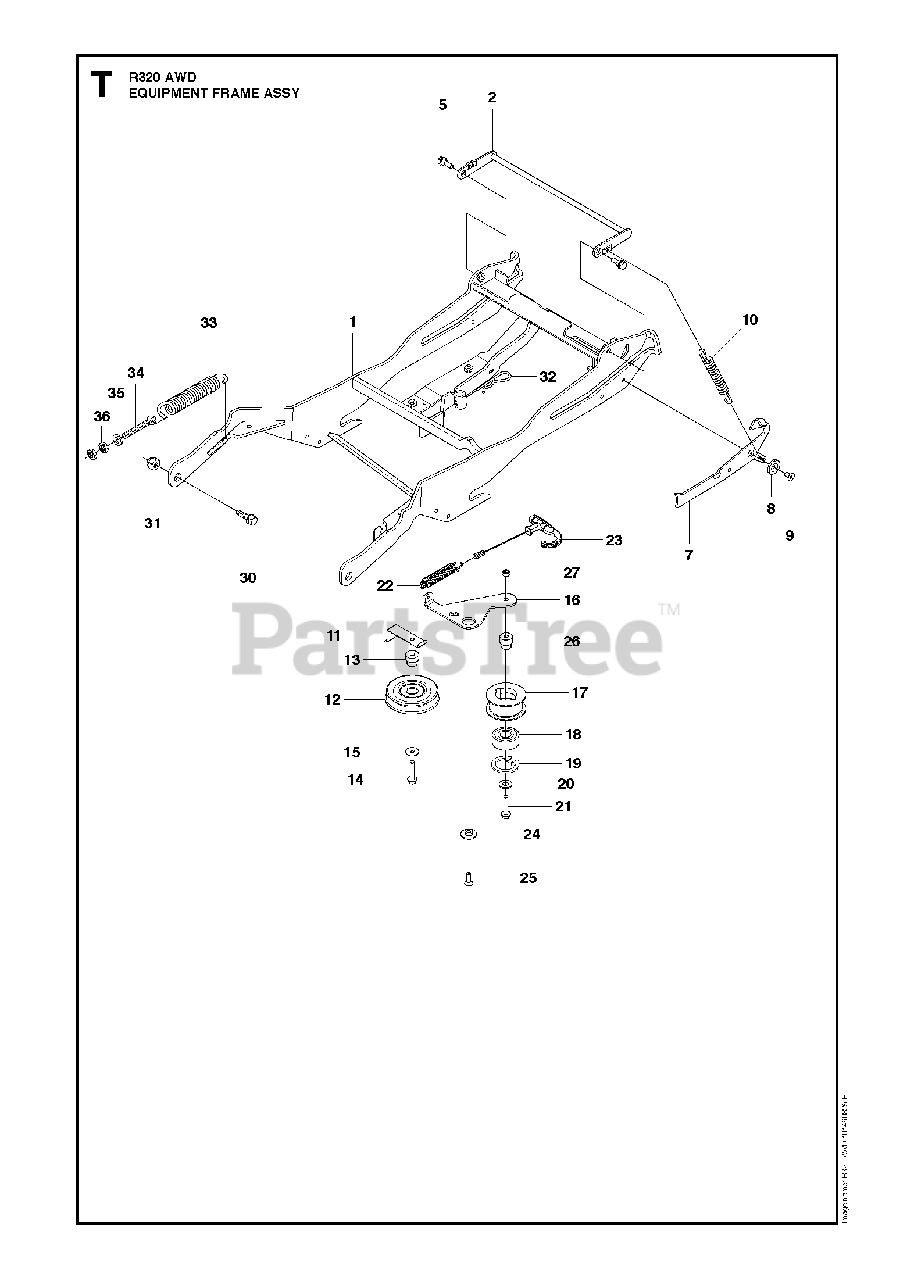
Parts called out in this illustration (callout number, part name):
1	EQUIPMENT FRAME
8	SPACER
9	SCREW IHCSFM
11	BELT GUIDE
17	BELT TENSIONER WHEEL ASSY
18	BALL BEARING 6004-2RS1
19	RETAINING RING
23	HANDLE ASSY
24	WASHER
27	LOCKNUT M8
31	Lock Nut, Fiber M12 DIN 985 Z/P
35	WASHER
36	NUT
